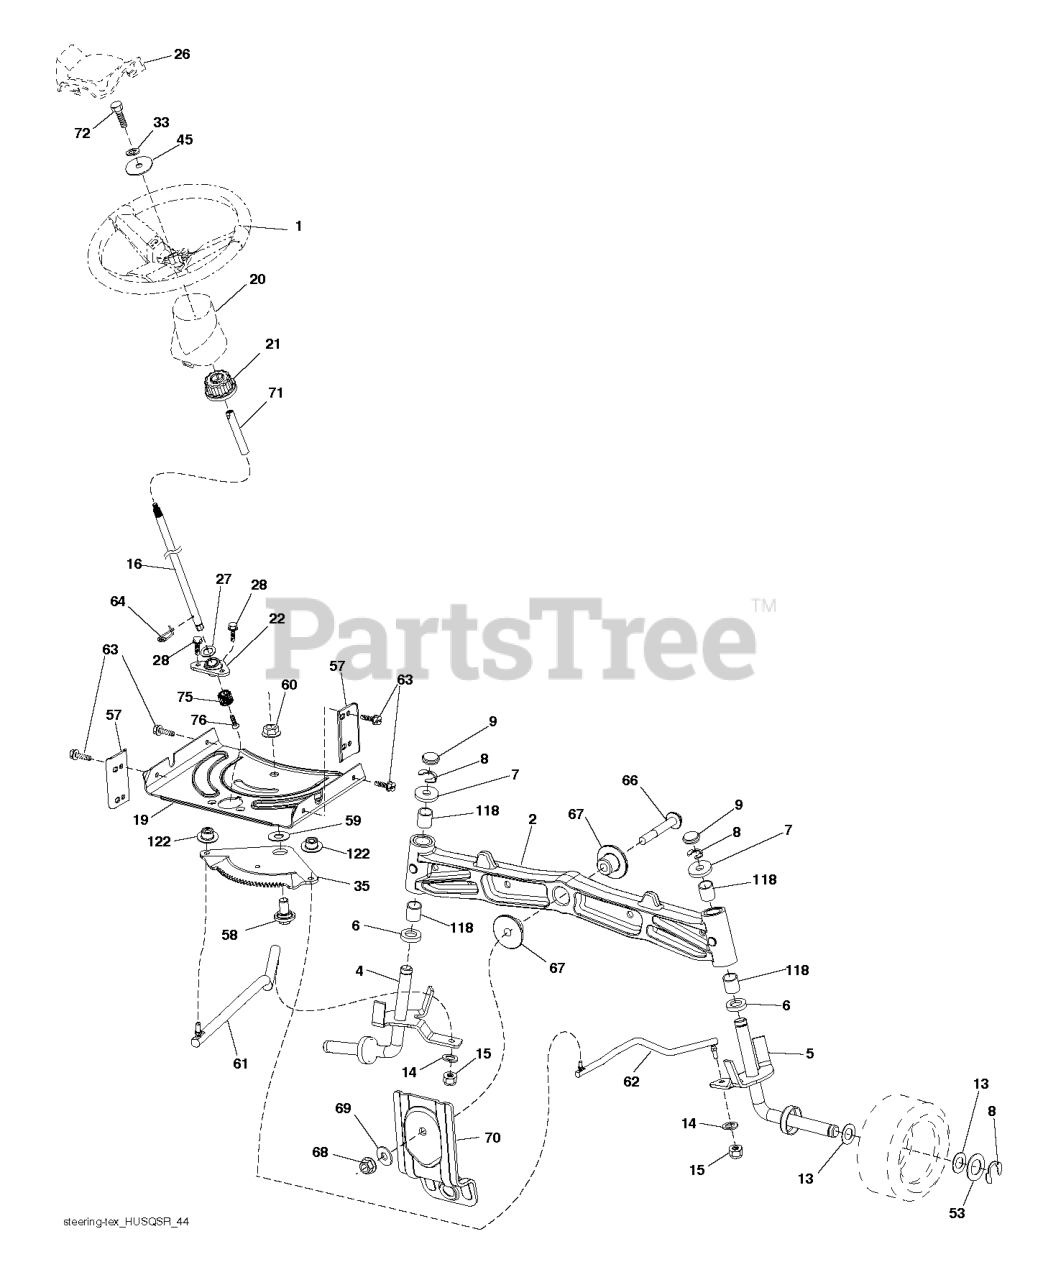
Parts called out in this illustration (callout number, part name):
1	WHEEL.STEER.HUSQ.SR.498.OVMLD
2	AXLE.SVC.ASM CAST IRON.TEX
4	SPINDLE.WELDED.LH.15"TEX
5	SPINDLE.WELDED.RH.15"T
6	WASHER THRUST
9	CAP.SPINDLE.BLACK
14	SLW 3/8 STD
15	NUT CROWNLOCK 3/8-24
16	3 HIGH.SHAFT-ZINC.PLATED
19	PLATE.STEER.DDL.NLT/NG
20	STEERING.BOOT.HUSQ.LT
21	ADAPTER, WHEEL STNG..
22	BEARING.SHAFT.STEER.LOWER.625
26	INSERT.CAP.WHL.STRG.HUSQ.PREM
27	WASHER LT
28	SCREW, 3/8-16X3/4
33	WASHER.LOCK.HVY.HLCL.SPR.5/16
35	GEAR.SECTOR.PLATE.DDL.
45	WASHER.11/32
53	WASHER.HARDENED
57	BRACKET.UPSTOP.TEX
58	BOLT.SHOULDER.SECTOR.P
59	WASHER.THURST.SECTOR.S
60	NUT FLANGE LOCK 5/8-11
61	DRAGLINK.LH.BALLSTUD.D
62	DRAGLINK.RH.BALLSTUD.D
63	SCREW
64	RETAINER.CLIP.SPRING.S
66	BOLT HEX FGHD 7/16-14 X 3 SERR
67	BUSHING.PM.FRONT AXLE
68	NUT.LOCK.FLANGE.7/16
69	WASHER.1.5X.505X.118
70	BRACKET.FRT.DECK.SUSP.RR.MT431
71	SHAFT.EXTEN.STRG.SPLINE
72	BOLT 5/16-18 X 4 W/PATCH
75	PINION.ZINC PLATED
76	SCREW HEAD SOCKET LRVB
118	BUSHING, AXLE CAST
122	CAP.GEAR.SECTOR.TEX
